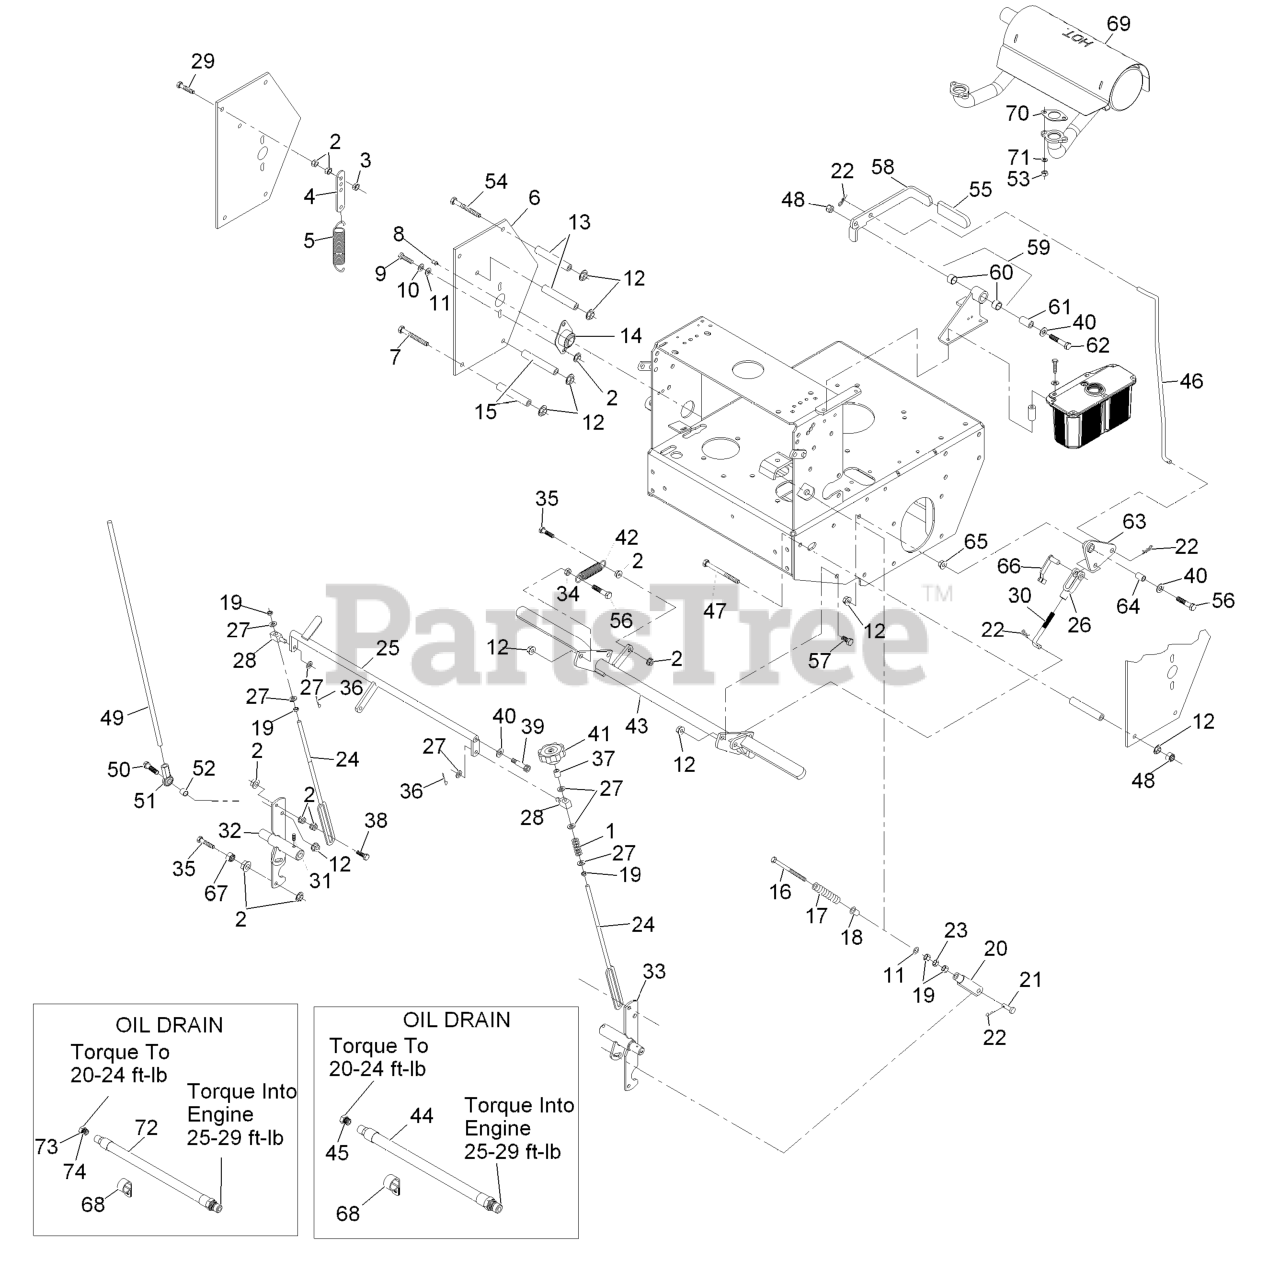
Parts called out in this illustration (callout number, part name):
1	SPRING-COMPRESSION
3	NUT-LOCK, NI
4	TAB-SPRING, EXTENSION
5	SPRING-EXTENSION
6	SHIELD-CONTROL
7	SCREW-HH
8	FITTING-GREASE
9	SCREW-HH
10	WASHER-LOCK
11	WASHER-FLAT
12	NUT-HHF, WHIZ
13	SPACER-SHIELD
14	BEARING-FLANGE, SIDE
15	SPACER-SHIELD
16	BOLT-RETURN, NEUTRAL
17	SPRING,COMPRESSION (NEUT)
18	BUSHING-FLANGED
19	NUT-HEX
20	YOKE-ADJUSTABLE
21	PIN-CLEVIS
22	PIN-COTTER
23	NUT-JAM
24	LINK-CONTROL, SPEED
25	CRANK-CONTROL, SPEED
26	YOKE-LINKAGE, BRAKE
27	WASHER-PLAIN
29	BOLT-TAP, HH
30	LINKAGE-LOWER
31	SCREW-SET
32	SHAFT-CONTROL, LH
33	SHAFT-CONTROL, RH
34	NUT-JAM
35	SCREW-HH, SPECIAL
36	PIN-COTTER
38	SCREW-HH
39	SCREW-HSH
40	WASHER-FLAT
41	KNOB-TRACKING
42	SPRING-IDLER
46	LINKAGE,UPPER- TTHP
47	SCREW-HH
48	NUT-LOCK, NI
49	LINK,DRIVE (PLTD)
50	SCREW-HH
51	JOINT-BALL END, LH
52	SPACER-TUBE, PUMP LINK
54	SCREW-HH
55	GRIP-LEVER
56	SCREW-HH
57	SCREW-HH
58	LEVER,PARK BRK W/DECAL
59	BRACKET ASM
60	SLEEVE-BUSHING
61	BUSHING-PIVOT
62	SCREW-HH
63	BELLCRANK ASM
64	BUSHING-PLASTIC
66	PIN-SPRING, CLEVIS
67	NUT-JAM
68	CLIP-LOOM
69	MUFFLER,HORIZONTAL
70	GASKET-EXHAUST
71	WASHER-LOCK
72	ASM, ENGINE OIL DRAIN HOS
73	PLUG-HH
74	O-RING
